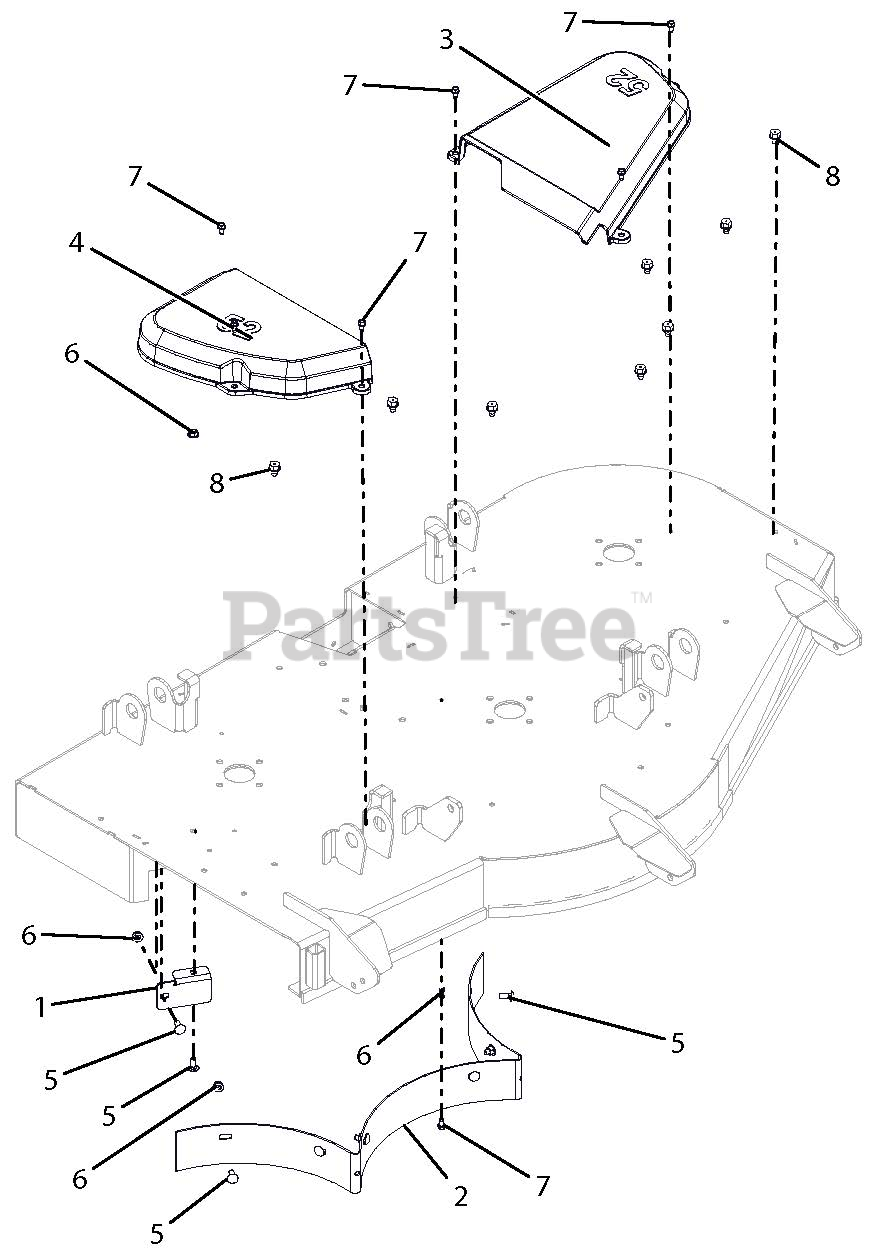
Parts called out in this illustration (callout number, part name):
1	STRIP, DEFLECTOR 52"
2	BAFFLE, REAR - REMOVABLE 52"
3	COVER, BELT 52" LH
4	COVER, BELT 52" RH
5	BLT-RDHDSQNK .31-18X.75 G5 YWZC
6	NUT, LK-TOP-FLG .312-18 YWZC
7	SCR-TAP .25-20X.50 HWH TR YWZ
8	SCR-TAP .38-16X.50 HWH TR YWZ
